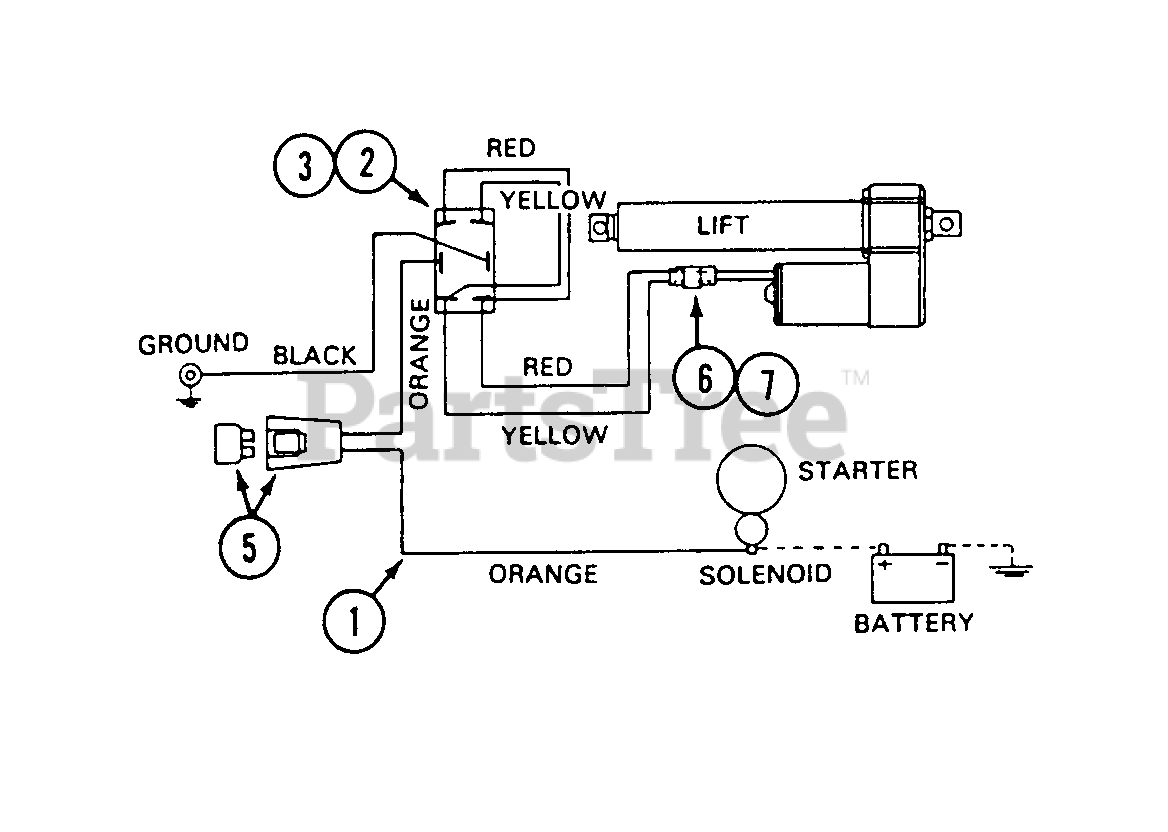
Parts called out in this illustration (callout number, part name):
1	HARNESS - wire
3	NUT - 15/32" - 32 with boot (switch mounting)
5	HOLDER - fuse
6	CONNECTOR - wire harness
7	CONNECTOR - lift actuator
